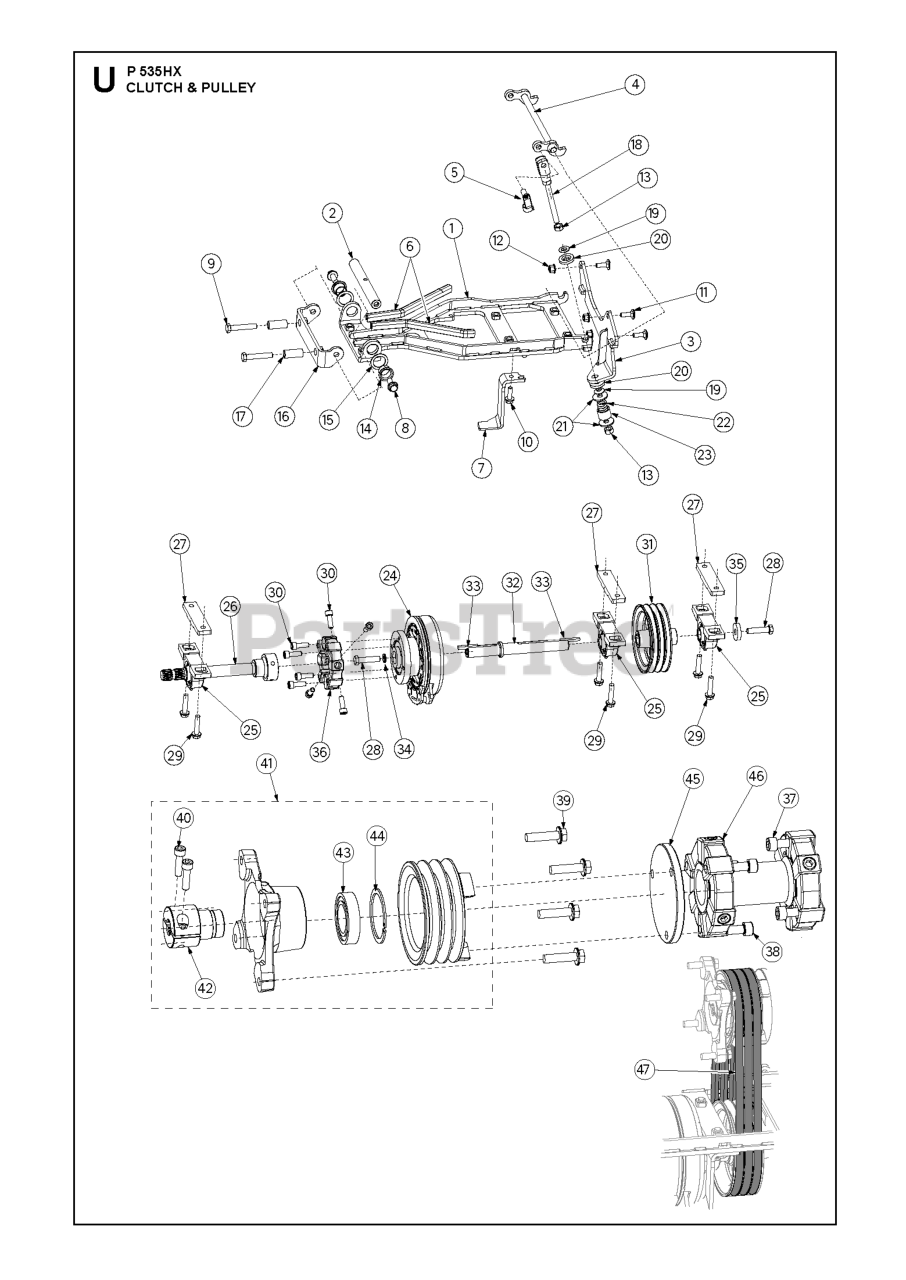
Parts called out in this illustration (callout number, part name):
10	BOLT
12	NUT FLANGE
29	COLLAR SCREW
30	SCREW IHSCM M10X30 12.9 ZPB L
36	RUBBER RING CLUTCH
38	SCREW IHSCM M10X45 12.9 ZPB L
